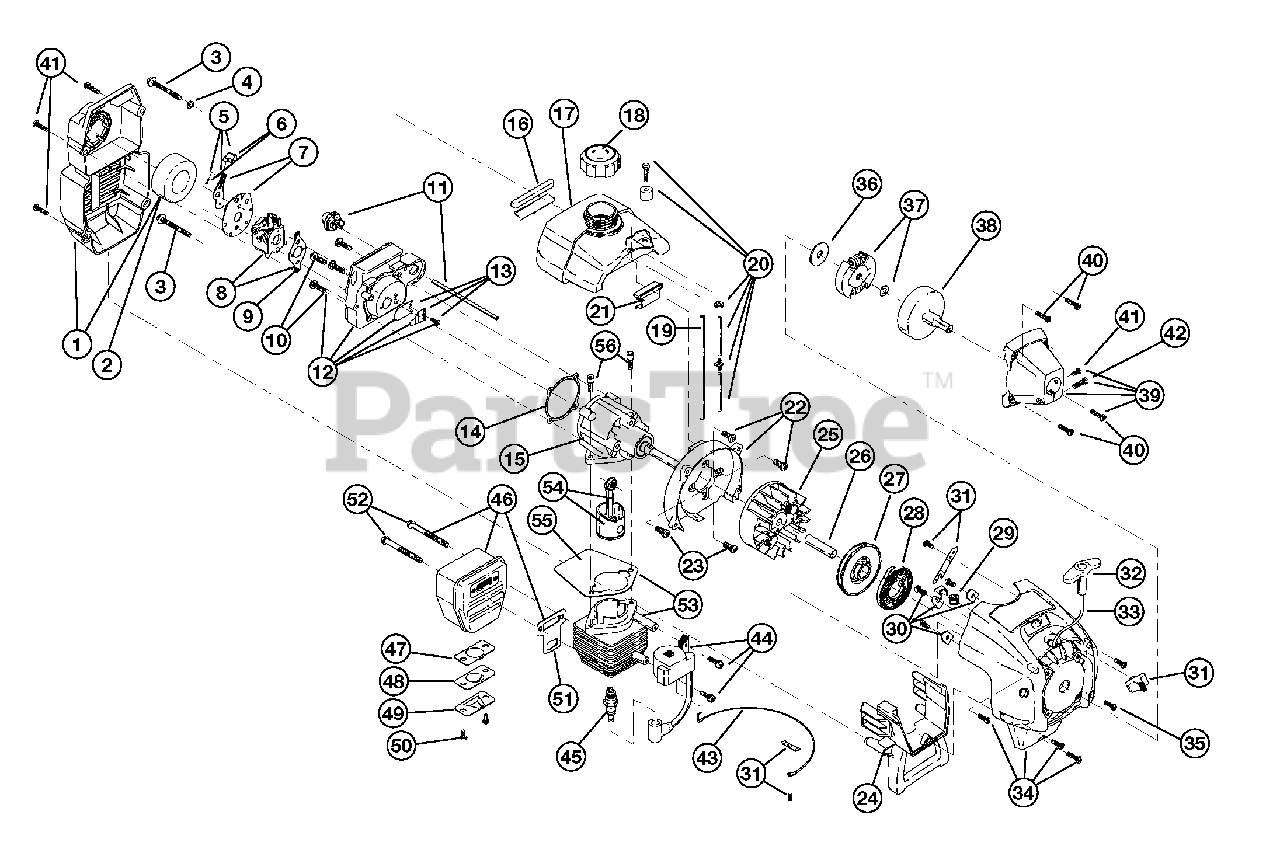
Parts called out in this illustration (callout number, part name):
1	Air Cleaner/Muffler Cover Assembly
2	Air Cleaner Filter
3	Carburetor Mounting Screw
4	Wavey Washer
5	Choke Lever Assembly
6	Choke Knob and Screw
7	Choke Lever and Plate
8	Carburetor Assembly W/Limiter Caps
9	Carburetor Gasket
10	Carb Mount Screw
11	Primer and Hose Assembly
12	Carb Mount Assembly
13	Reed Assembly
14	Carburetor Mount Gasket
15	Crank Case Service Assembly
16	Rear Mounting Pad
17	Fuel Tank Assembly
18	Fuel Cap
19	Fuel Return Line
20	Fuel Line Assembly
21	Front Mounting Pad
22	Shroud Assembly
23	Shroud Screw
24	Shroud Extension and Stand
25	Flywheel
27	Recoil Pulley
28	Recoil Spring
29	Rope Guide
30	Pulley Retainer Assembly
31	Switch Assembly
32	Pull Handle
34	Starter Housing Assembly
35	Housing Screw
36	Clutch Washer
37	Clutch Rotor Assembly
38	Clutch Drum
39	Clutch Cover Assembly
40	Cover Screw
41	Anti-Rotation Screw
42	Clamping Screw
43	Wire Lead
44	Module Assembly
45	Spark Plug
46	Muffler Assembly
47	Spark Arrestor Screen
48	Spark Arrestor Plate
49	Spark Arrestor Hood
50	Spark Arrestor Screw
51	Exhaust Gasket
52	Muffler Mounting Bolt Assembly
53	Cylinder Assembly
54	Piston and Rod Assembly
55	Cylinder Gasket
56	Cylinder Bolt
